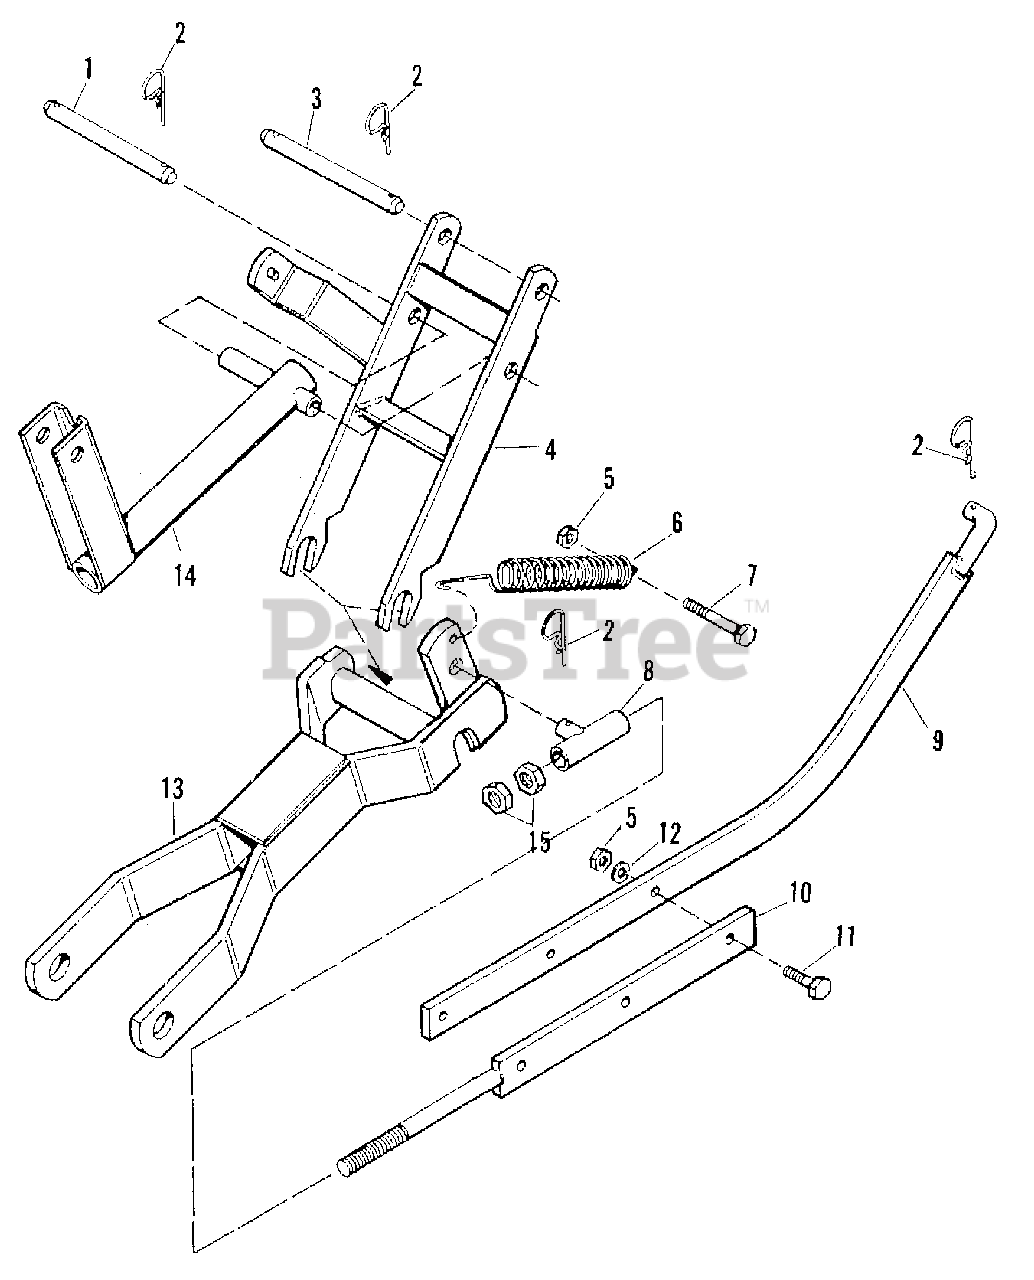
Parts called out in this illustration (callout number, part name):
4	STRUT ASSEMBLY
5	NUT, Hex Full, 3/8-16
7	SCREW, Hex Cap, 3/8-16 x 2-1/2
8	GUIDE TUBE ASSEMBLY
9	LIFT ARM ASSEMBLY, Front
10	LIFT ARM ASSEMBLY, Rear
11	SCREW, Hex Cap, 3/8-16 x 1-1/4
12	WASHER, Lock, 3/8
13	HITCH & LIFT ASSEMBLY
15	NUT, Hex, 1/2-20
